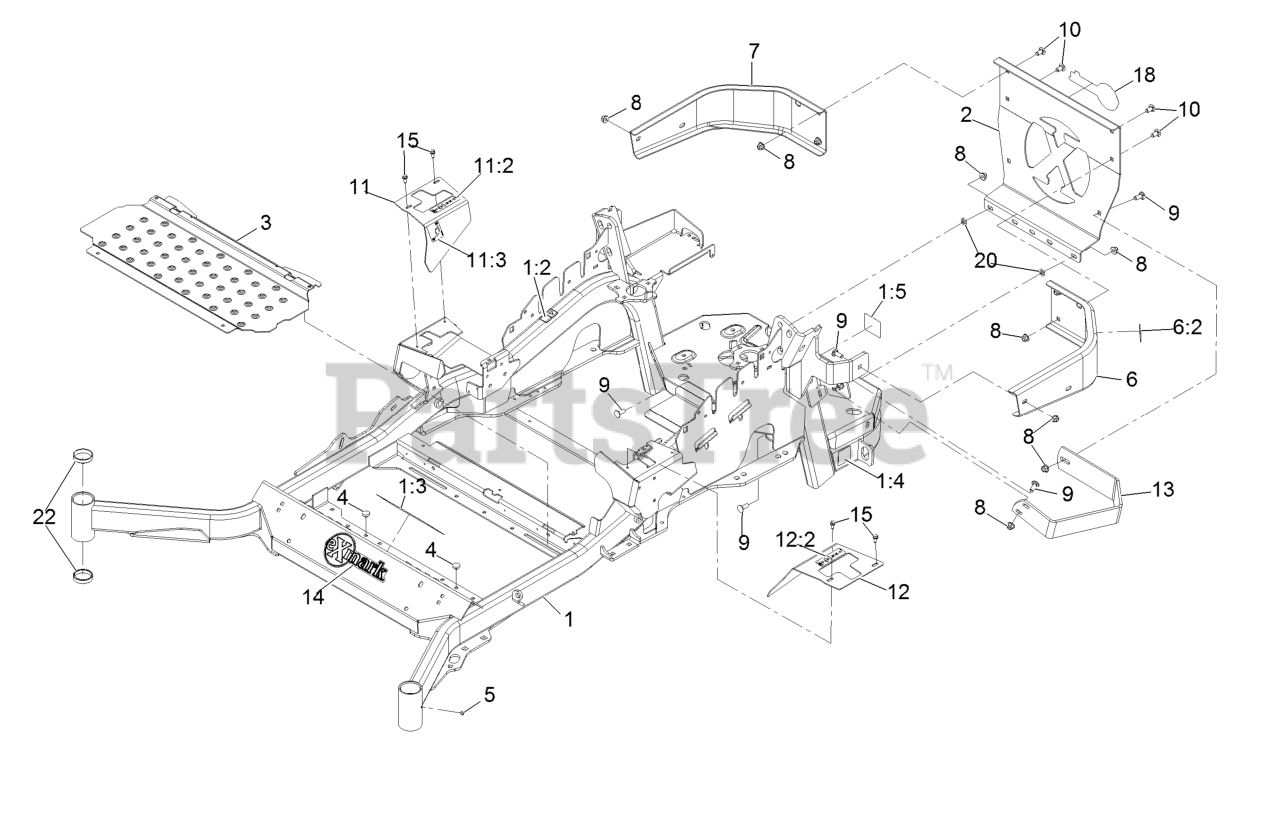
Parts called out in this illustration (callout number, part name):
1	Mainframe ASM
1:2	Decal-Warning
1:3	Decal-Danger
1:4	Decal-Hazard, Pinched Finger
1:5	Decal-Spark Arrester
2	Plate,Rear Guard
6	LH Bumper ASM
6:2	Decal-Warning
7	Bumper-RH
8	Nut-Nyloc 3/8-16 Flg
9	Bolt-Carriage 3/8-16 X 1
10	Bolt-Carriage 3/8-16 X 3/4 ASM
11	RH Motion Control Cover
11:2	Decal-Control, Motion
11:3	Decal-Park Brake, CE
12	LH Motion Control Cover ASM
12:2	Decal-Control, Motion
13	Guard-Muffler
14	Decal-Exmark
15	Screw-HWH 1/4-20 X .62
18	Decal-Exmark Logo
20	Nut-Push 3/8-16
22	Cup-Bearing Tapered Roller
